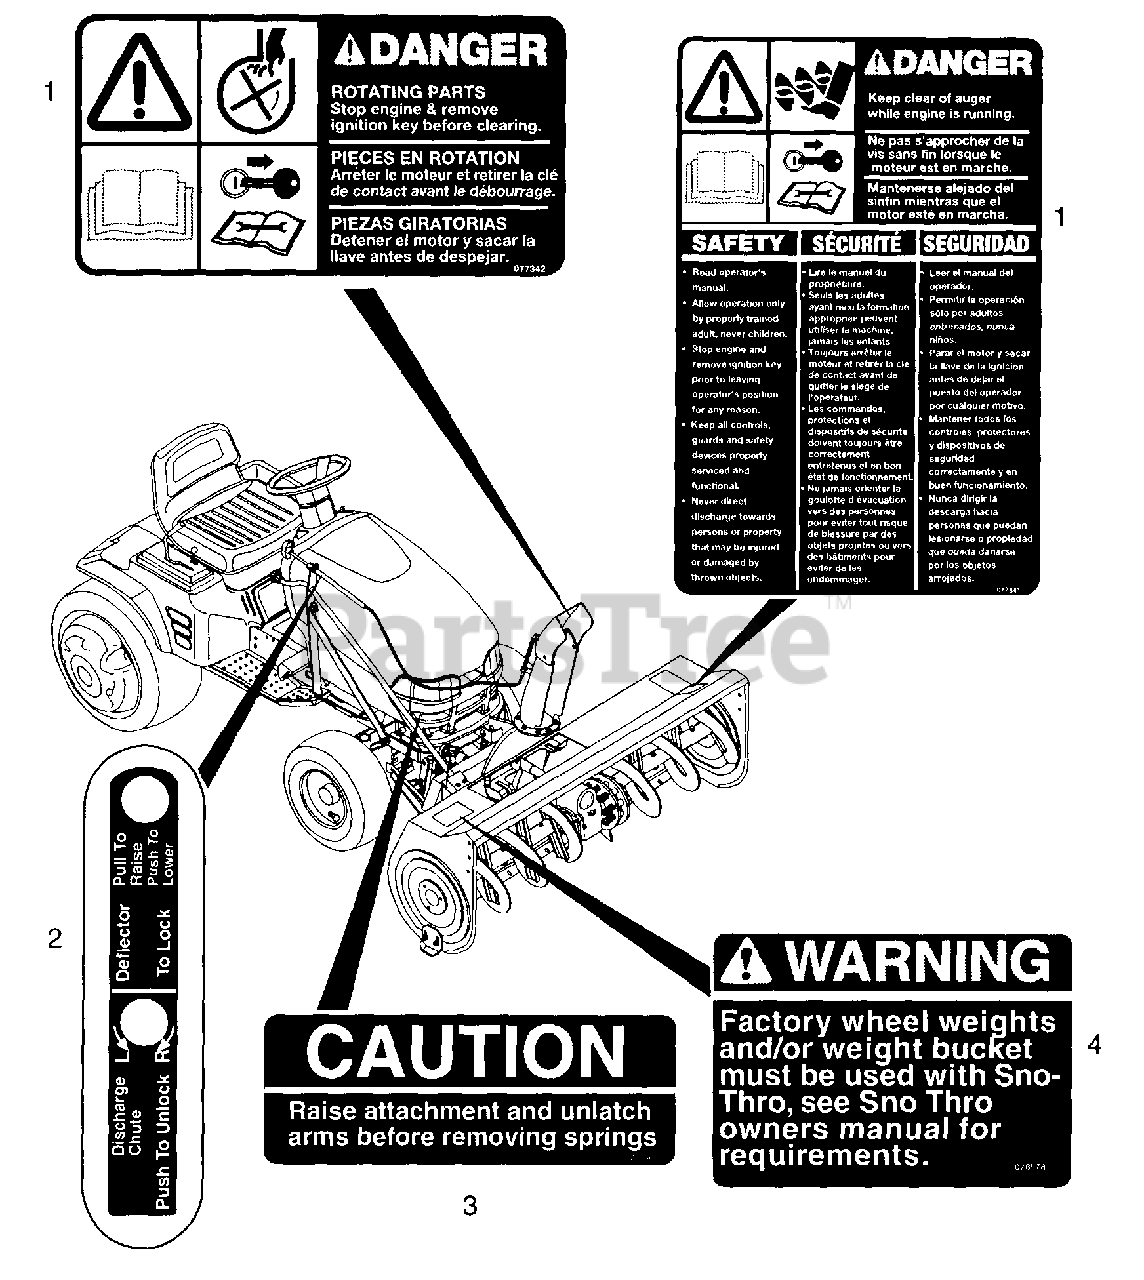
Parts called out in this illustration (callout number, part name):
1	DECAL SET - DANGER
2	DECAL- CHUTE CRANK
3	DECAL - CAUTION
4	WARNING WHEEL WEIGHT DECAL
